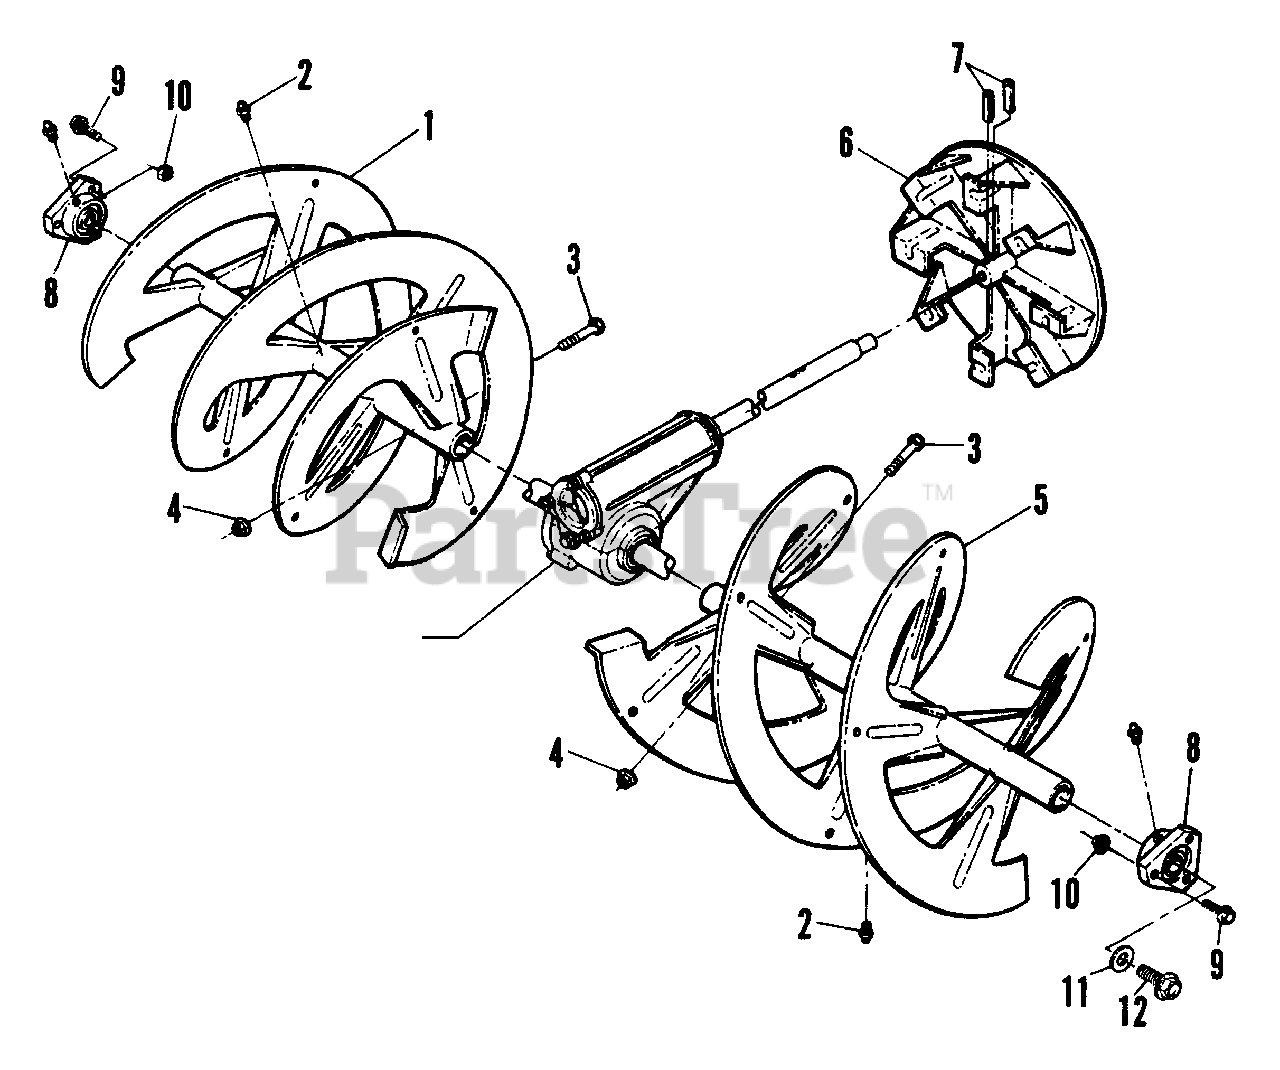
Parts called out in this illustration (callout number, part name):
1	AUGER, Right Side
2	LUBE FITTING, Straight (press-fit for .187 dia. Hole)
3	BOLT, 5/16-18 x 1-7/8" Shear
4	LOCKNUT, 5/16 - 18 Hex Flange
5	AUGER, Left Side
6	FAN, Impeller
7	PIN, Drive Lock
8	BEARING, Auger Shaft
9	BOLT, 1/4 - 20 x 3/4 Hex Flange Lock
10	NUT, 1/4 - 20 Hex Flange
11	WASHER, 3/8" Flat
12	SCREW, 3/8 - 16 x 3/4 Self Tap
